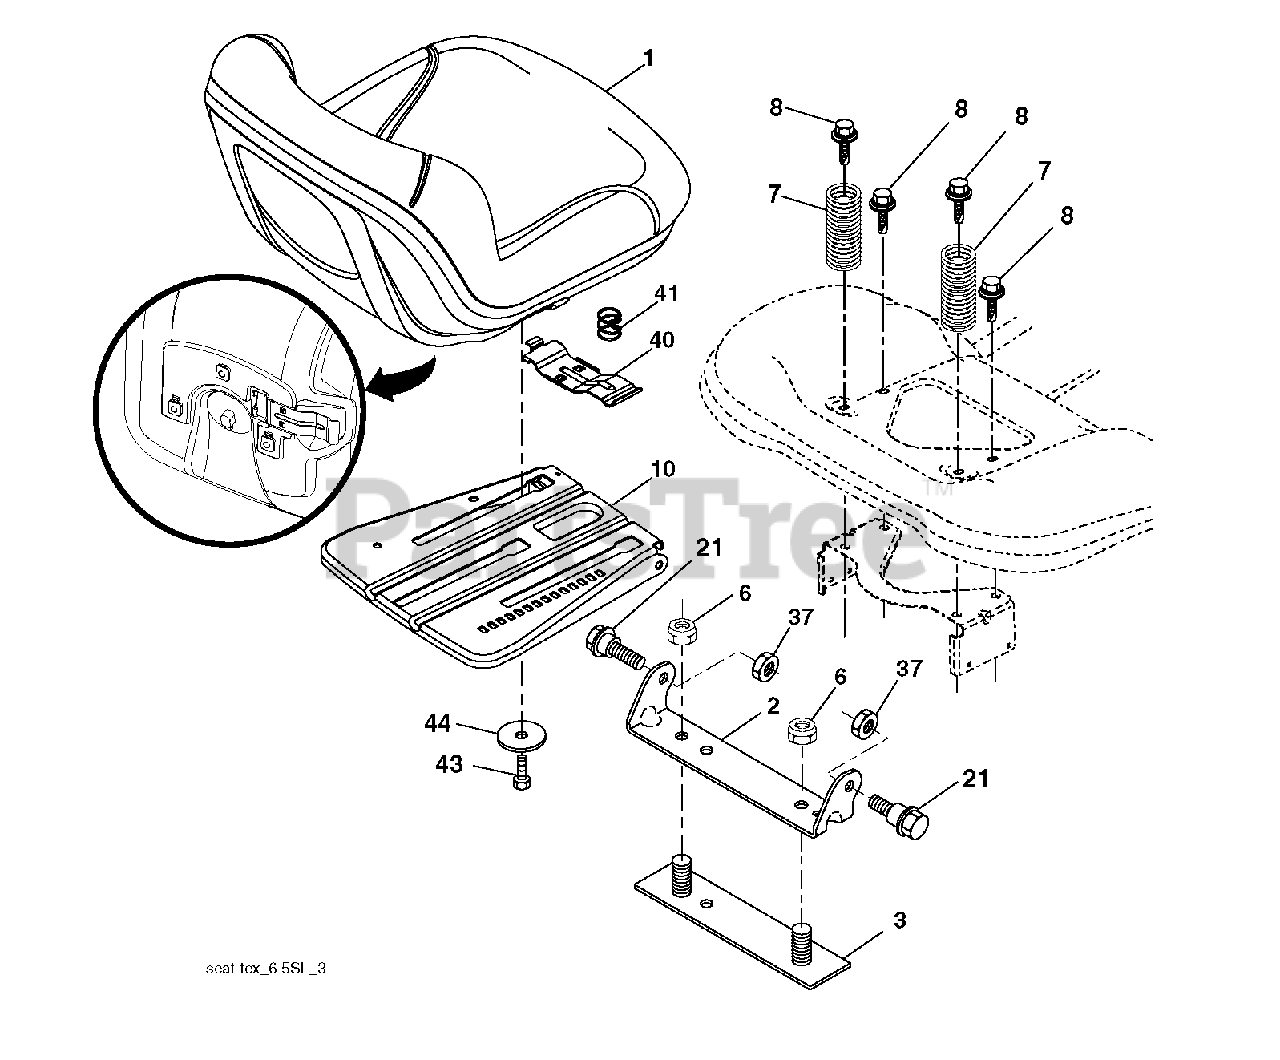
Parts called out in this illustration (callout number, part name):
1	SEAT.TH154.GREY.HUS.ARMREST
2	BRKT.PIVOT.FENDER
3	STRAP
6	NUT
7	SPRING COMPRESSION
8	BOLT, 5/16-18 X 1 3/4
10	PAN.ASM.SEAT.3PT
21	BOLT.SHOULDER.5/16-18
37	NUT.71038.31-18.HEX.NYLOCK
40	HANDLE.SLIDE.SEAT.TEX.GREY
41	SPRING.LATCH.SEAT.TEX
44	WASHER 13/32 X 2-3/8 X 12GA
